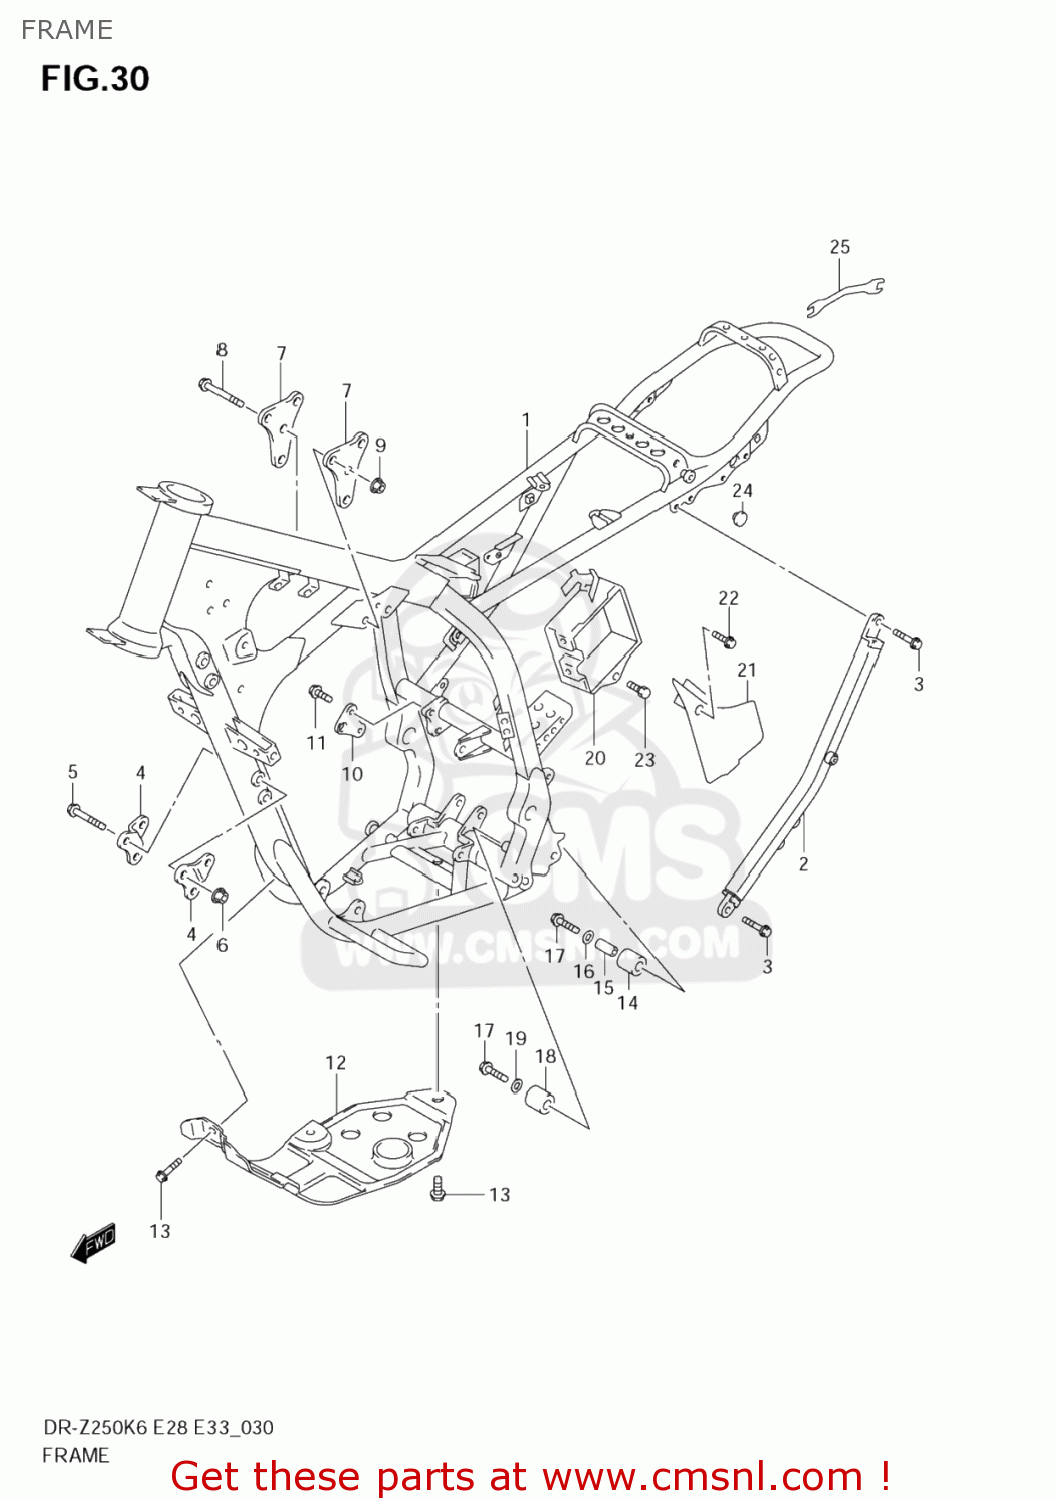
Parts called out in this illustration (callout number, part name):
1	FRAME(SILVER)
2	TUBE,FRAME SIDE,L
3	BOLT(8X20)
4	PLATE,HEAD MTG FR
5	BOLT(8X65)
6	NUT
7	PLATE,HEAD MOUNT RR
8	BOLT
9	NUT
10	PLATE,ENGINE MOUNT RR,R
11	BOLT(8X16)
12	PROTECTOR,ENGINE
13	BOLT
14	ROLLER,CHAIN CONTROL UPR
15	SPACER(8.6X12X27.1)
16	WASHER
17	BOLT(8X38)
18	ROLLER,CHAIN
19	SHIM(8X12X1)
20	HOLDER,BATTERY
21	CAP,BATTERY HOLDER
22	BOLT(6X16)
23	BOLT(6X17.5)
24	CAP(OD:20)
25	SPANNER,OPEN
